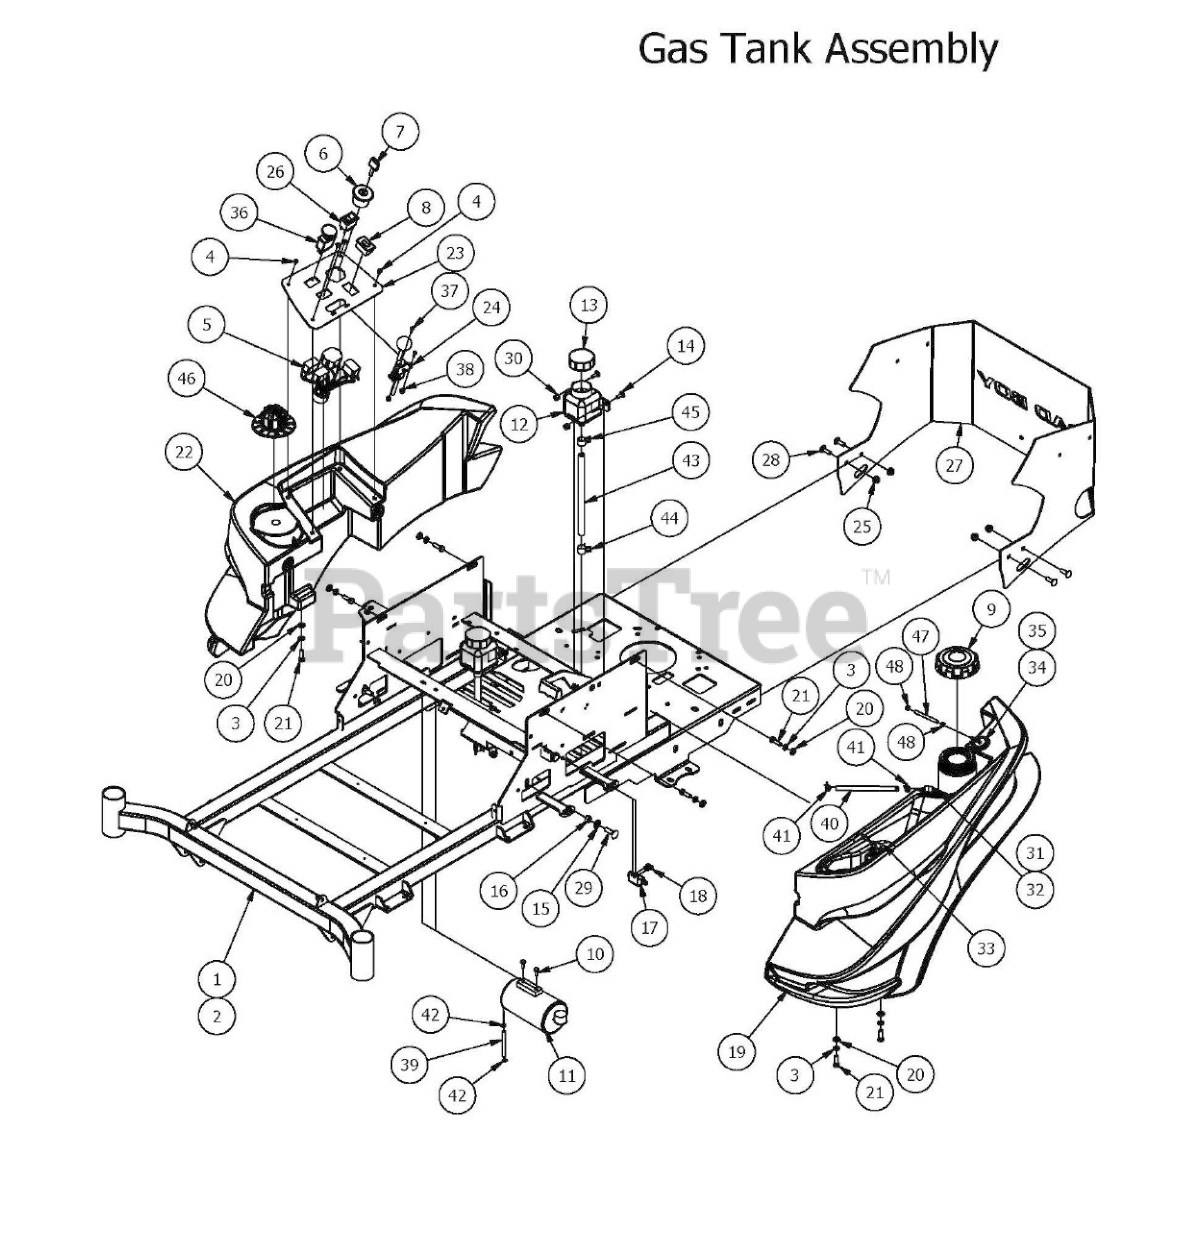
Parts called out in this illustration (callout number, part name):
1	ZT 48" Frame
2	ZT 54" and 60" Frame
3	5/16" Lock Washer
4	10-32 x 3/8" Button Socket Head Bolt
5	Universal Wire Harness
6	Ignition Switch
7	Ignition Key
8	Tachometer
10	M6-1.0 X 16MM Hex Bolt
11	Carbon Canister
12	350ml Expansion Tank
13	Hydraulic Tank Cap
14	1/4" x 3/4" Carriage Bolt
15	3/8" Flat Washer
16	3/8-16 Hex Nuts Zinc
17	Safety Switch
18	12-24x 1/2 HWH Bolt
19	Left Fuel Tank
20	5/16" Flat Washer
21	5/16" x 1" Bolt
22	Right Side Console
23	Control Panel
24	Throttle Lever Assembly
25	5/16" Nylock Flange Nut Zinc
26	Rocker Deck Lift Switch
27	2017 ZT Rear Plate
28	5/16" x 1" Carriage Bolt
29	3/8" x 1 1/4" Carriage Bolt
30	1/4-20 Nylon Insert flange Nut
31	Pick-Up Grommet
33	Fuel Gauge w/Grommet
34	Rollover Valve
35	Rollover Valve Grommet
36	PTO Switch
37	10-24 X 5/8 BS Button Head Bolt
38	10-24 Nylon Insert Locknut
39	3/16 Vinyl Tubing
40	1/4" Fuel Line Hose
41	1/4 Fuel Hose Clamp
42	3/16" Vinyl Hose Clamp
43	3/8" Clear Hose
44	3/8" Hose Clamp
45	1/2 Hose Clamp
46	MZ/ZT Deck Height Dial
47	1/4" Vinyl Tubing
48	3/16 Vinyl Clamp
